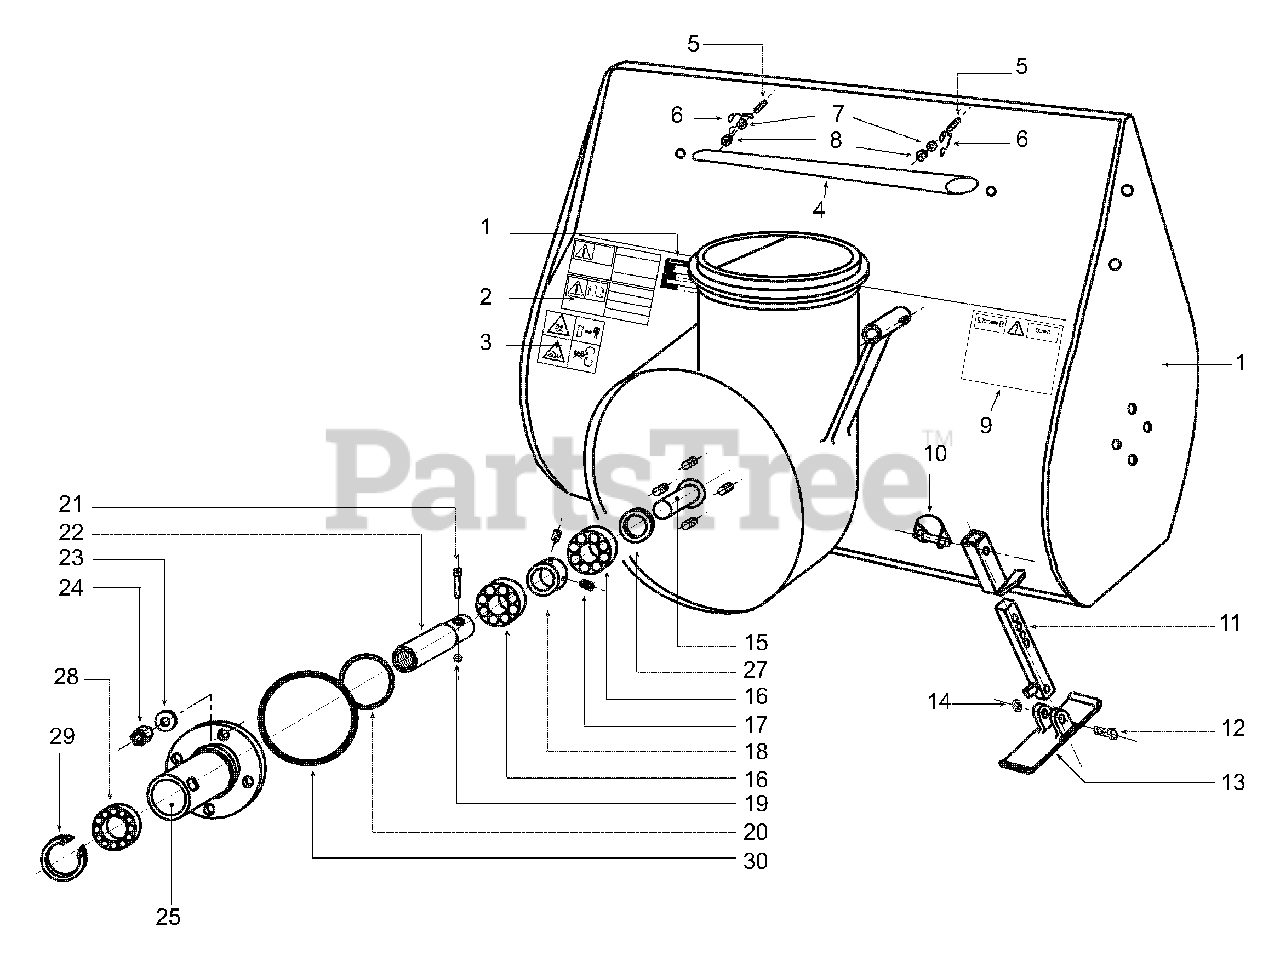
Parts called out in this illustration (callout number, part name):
1	Label - "Machine Data"
2	Label - "Instruction Manual And Danger"
3	Label - "Safety Distance And Rotating Parts"
4	Stick For Clogging Removing
5	Hexagonal Head Screw M6 x 15 - Din 933
6	Spring For Stick Clamping
7	Washer 5.5 x 10 x 1 - Din 125a
8	Self Locking Nut M6 - Din 982
9	Label - "Safety Bolt Replacement"
10	Fast Pin Ø8 x 45
11	Adjustable Rod For Slide
12	Hexagonal Head Screw M10 x 45 - Din 931
14	Self Locking Nut M10 - Din 982
16	Bearing 6305 2rs - 25 x 62 x 17
17	Grub - Screw M8 x 10 - Din 914-45h
18	Fastening Ring 25 x 37 x 11
19	Nut M8 - Din 934
20	O-ring 162 - 59 x 3.53
21	Safety Bolt For Coupling Box
22	Coupling Box (Power Take Off)
23	Washer 13 x 24 x 2.5 Din 125a
24	Self Locking Nut M10 - Din 982
25	Flange (4 Holes Ø12)
26	Label - "Rapid"
27	Distance Ring Ø 25.5 x 35 x 2.5
28	Bearing 6007 2rs - 35 x 62 x 14
29	Snap Ring Ø 62 - Din 472-1
30	O-Ring 4550
